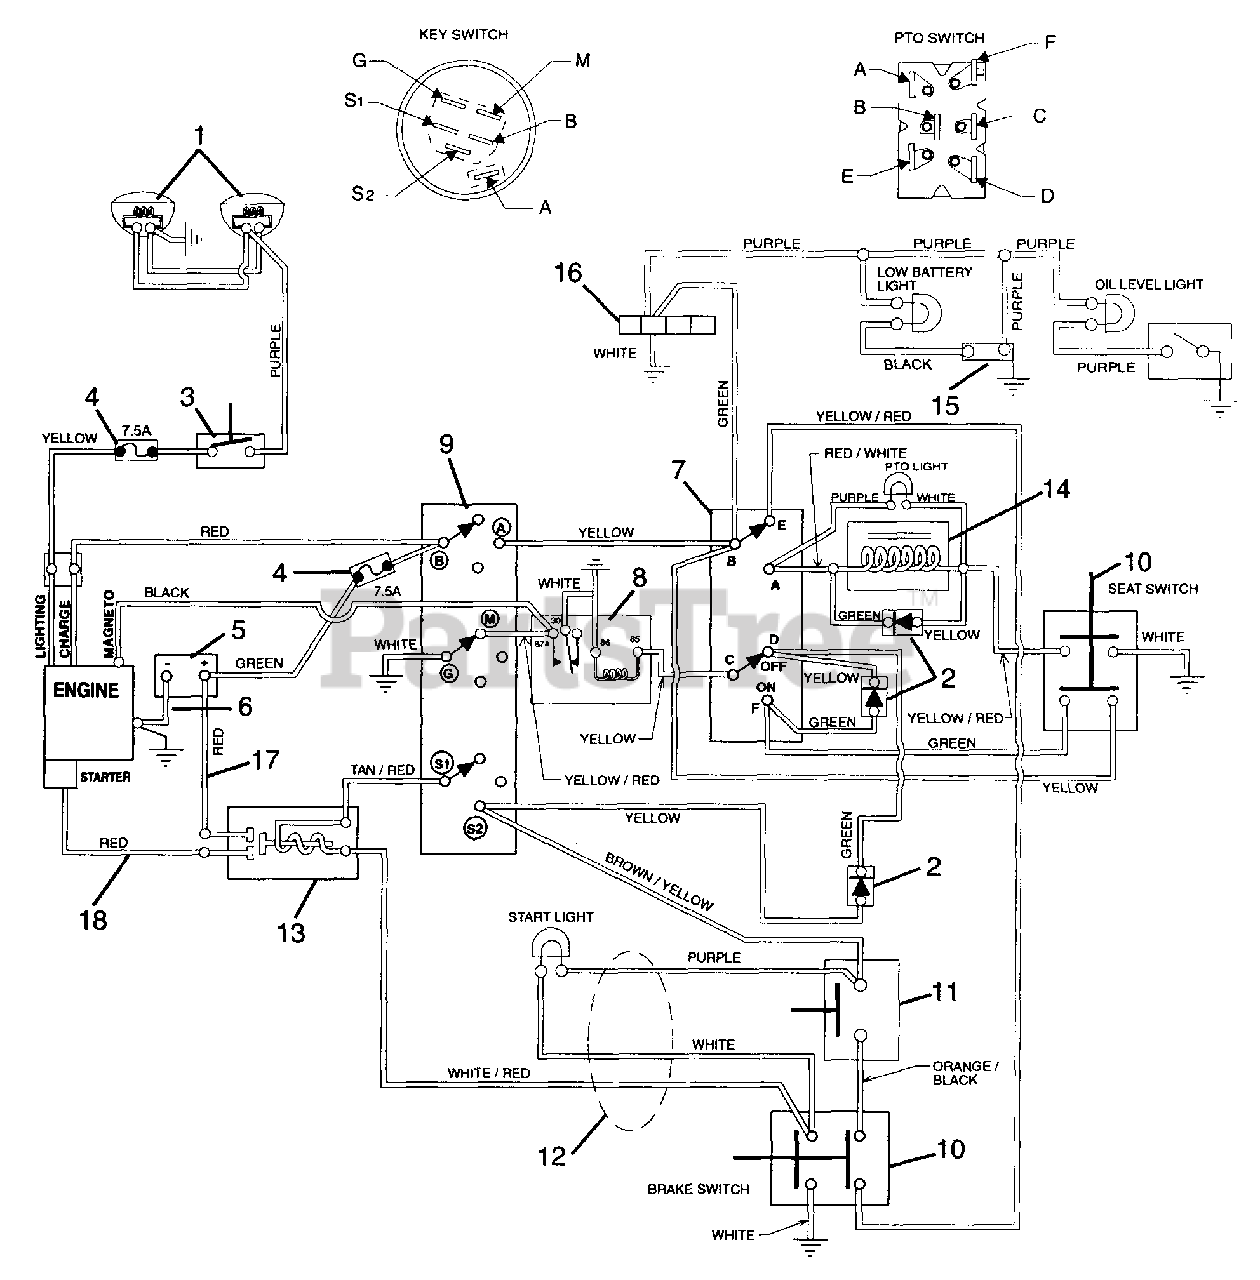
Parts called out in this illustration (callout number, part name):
1	HEADLIGHT- L.H.
2	DIODE & HOUSING
3	LIGHT SWITCH
4	7.5 Amp Fuse
5	BATTERY W/TUBE
6	GROUND CABLE .31X22.00X.31
7	SWITCH ASSEMBLY- PTO
8	RELAY
9	KEY SWITCH
10	SWITCH- DOUBLE POLE N.O./N.O.
11	SWITCH, NEUTRAL START N.C.
12	WIRE HARNESS- YT13G
13	SOLENOID
14	ELECTRIC CLUTCH/BRAKE(1.8AMP)
15	VOLTAGE SENSOR
16	HOUR METER W/ LEADS
17	START CABLE 22"
18	STARTER CABLE 6.75"
